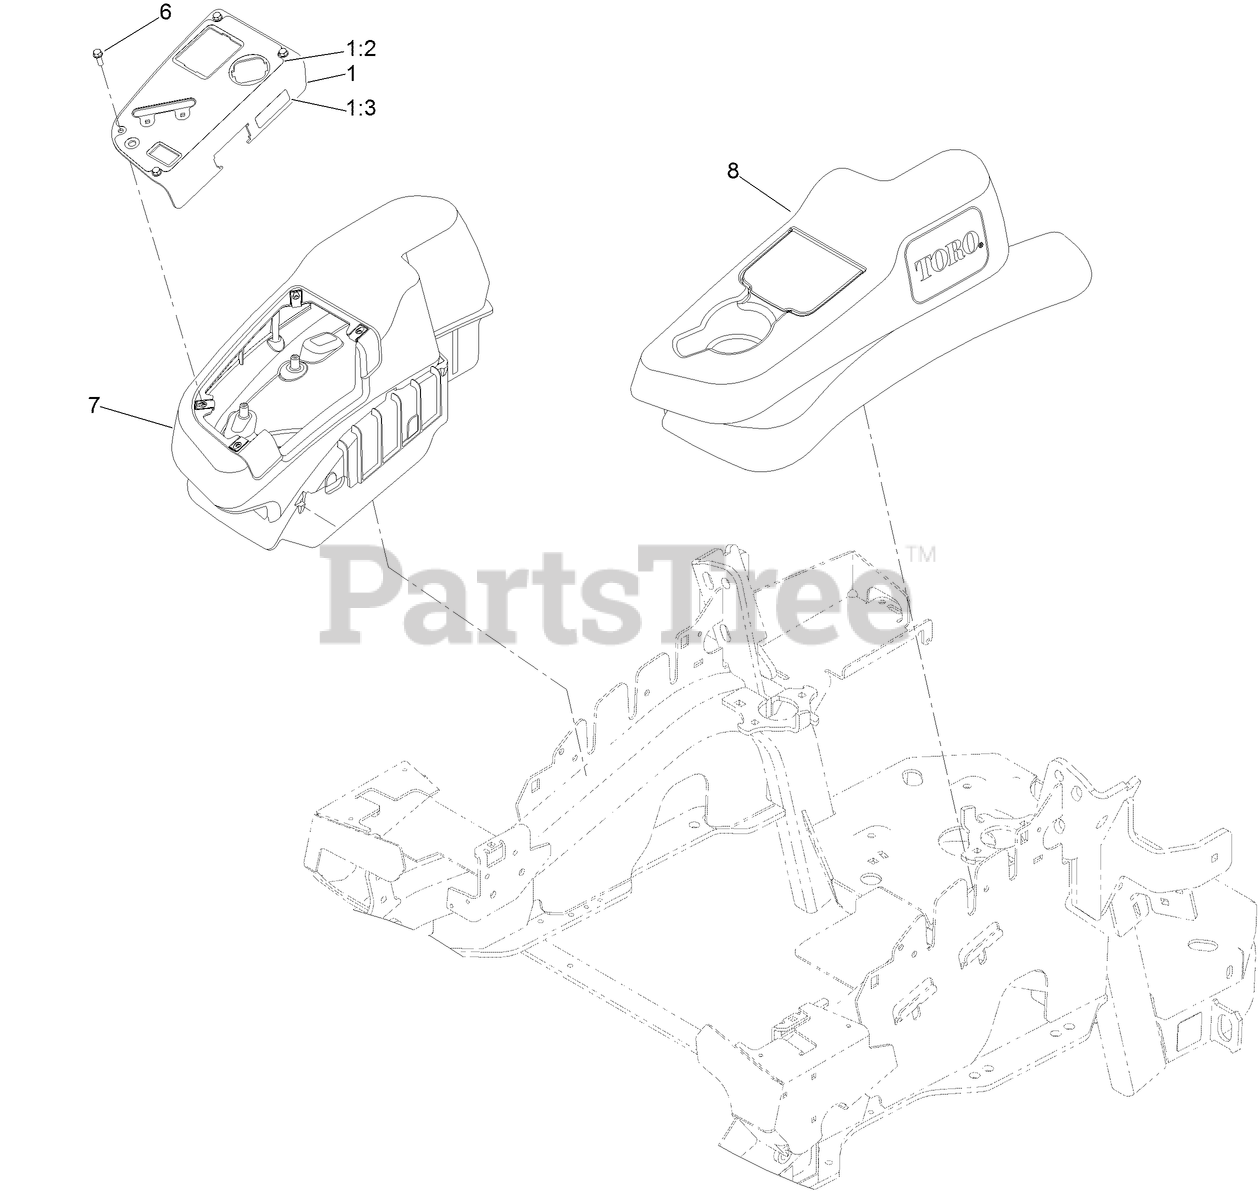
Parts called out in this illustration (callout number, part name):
1	CONTROL PANEL ASM
1:2	DECAL-CONTROL PANEL
1:3	DECAL-FUSES
6	SCREW-HWH
7	RH NARROW FENDER/CONSOLE ASM
8	LH NARROW FENDER/CONSOLE ASM
